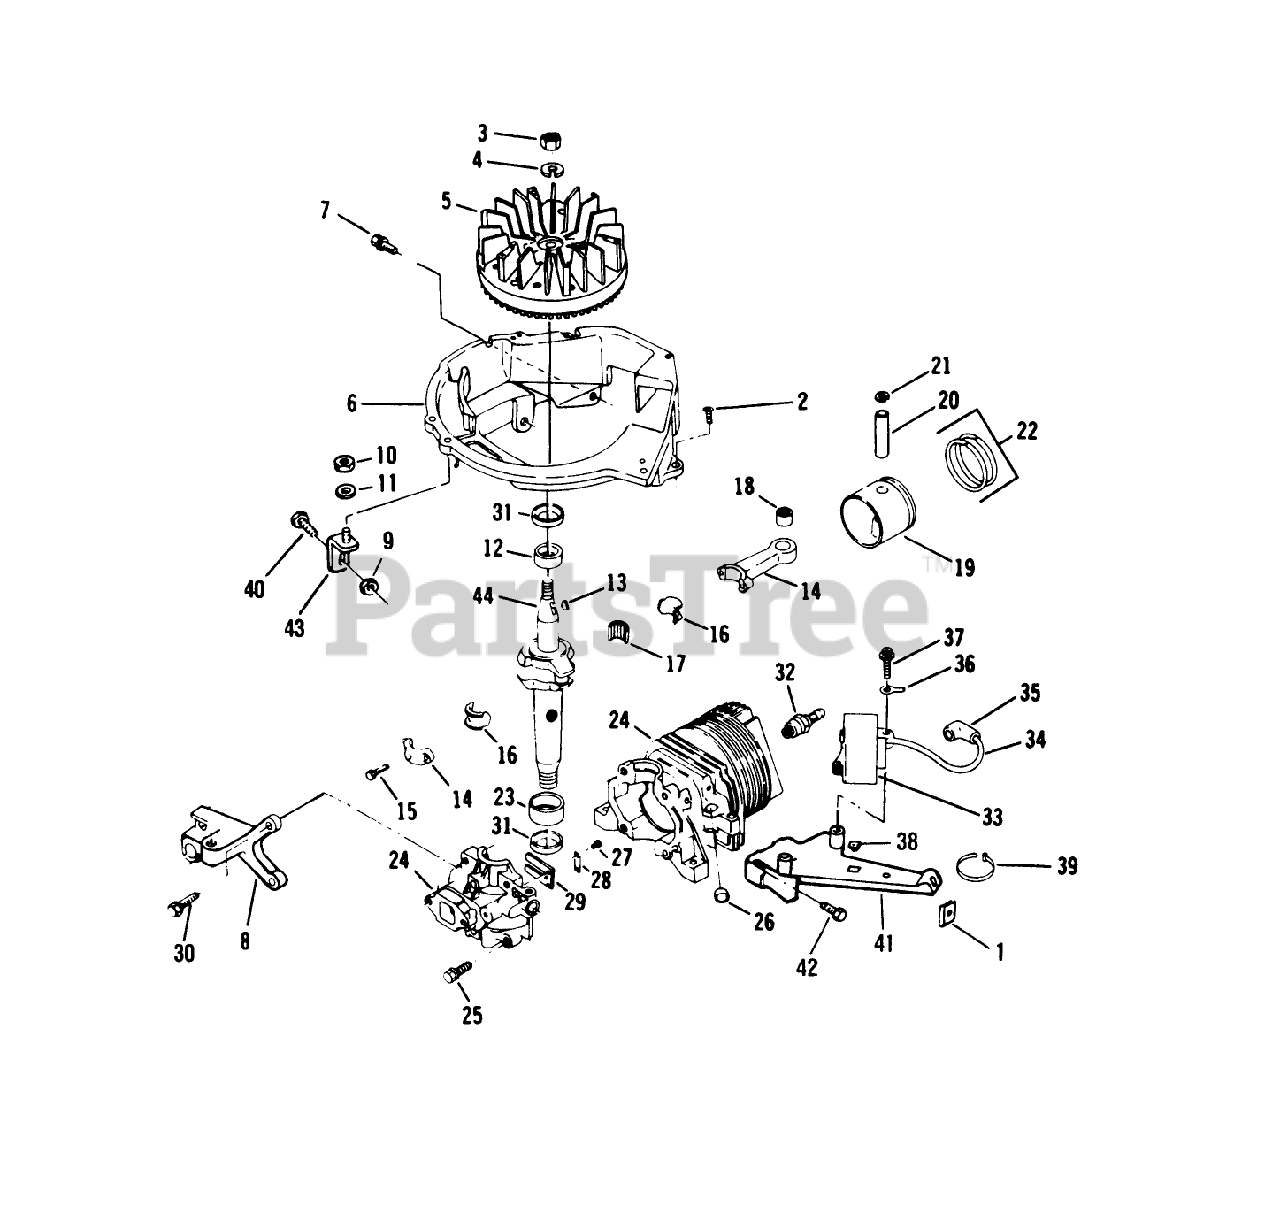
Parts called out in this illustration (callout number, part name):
1	NUT-SPEED
2	SCREW F
3	NUT
5	FLYWHEEL ASSY F
7	SCREW-SEMS
8	BRACKET-BRAKE F
9	NUT-LOCK F
10	LOCKNUT E
11	WASHER S
12	BEARING V
13	KEY
15	SCREW-HSH
16	LINER ASM
17	BEARING-NEEDLE
18	BEARING AY F
21	RING-RETAINING
23	BEARING V
25	SCREW S
26	PLUG-CORE VF
27	SCREW-HH
28	PLATE-BACKUP, REED
31	SEAL-OIL
34	HT LEAD&COVER XEV
36	TERMINAL S
38	NUT-CLIP
40	BOLT F
43	BRACE AY F
